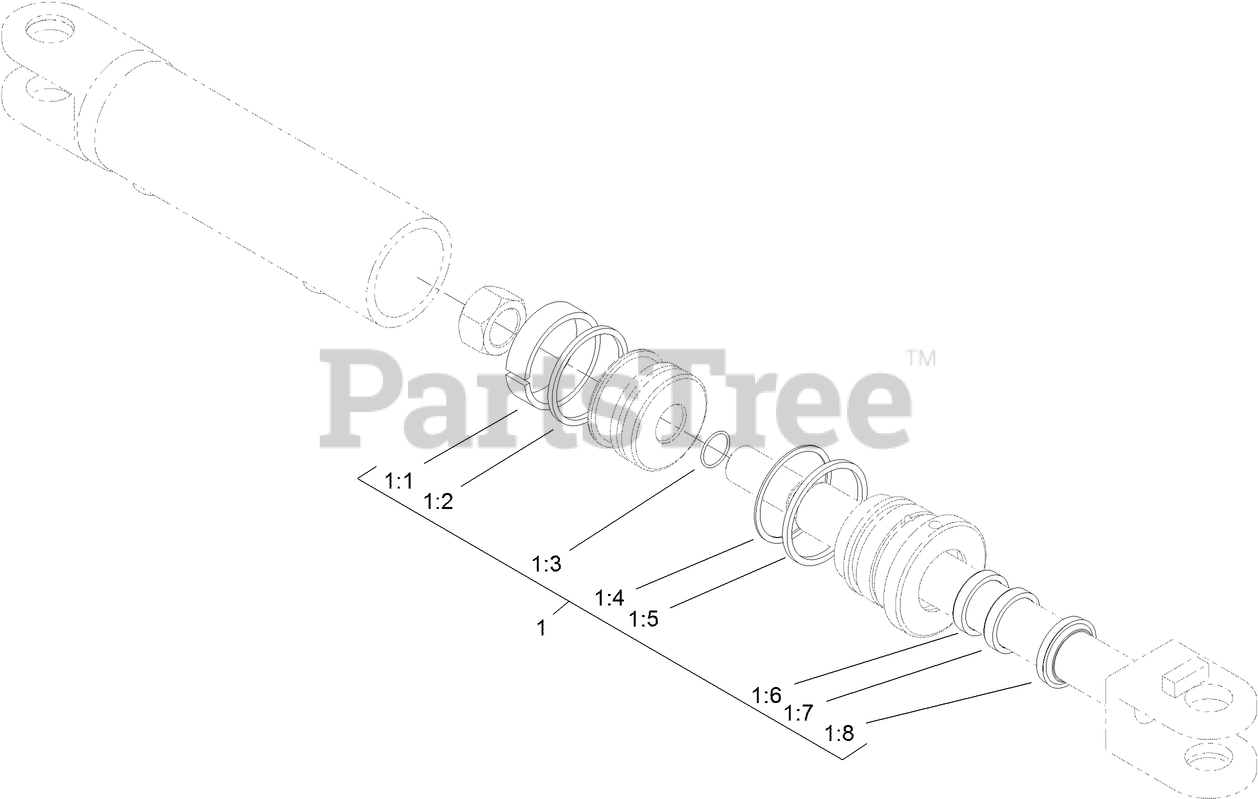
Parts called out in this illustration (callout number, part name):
1	KIT-SEAL
1:1	Seal-Piston
1:2	Seal-Piston
1:3	O-RING
1:4	SEAL-TUBE
1:5	SEAL-TUBE
1:6	SEAL-ROD
1:7	SEAL-ROD
1:8	WIPER
